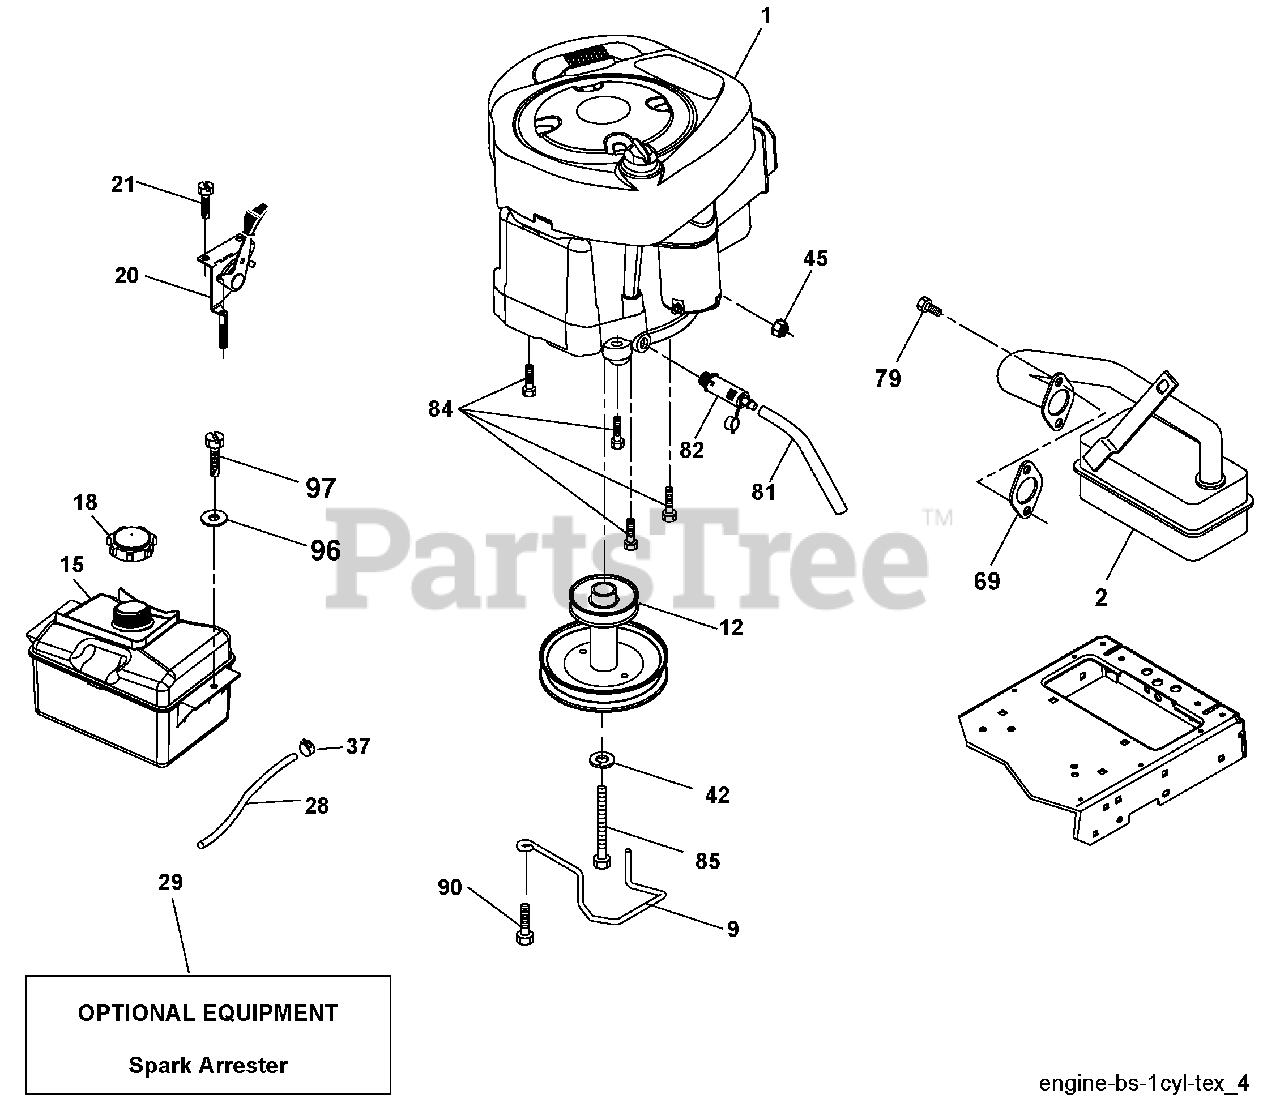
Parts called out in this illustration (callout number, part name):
2	Muffler
9	Keeper Belt Engine
12	Pulley Engine
15	Tank Fuel 1.50
18	Cap Asm.
20	Control Throttle/Choke
21	Screw #10 x 0.750 BOS Thread
28	Fuel Line
29	Spark Arrester Kit
37	Clamp Hose
42	Washer Lock 7/16
45	Nut Keps Hex 1/4-20 unc
69	Gasket
79	Screw Socket Hd. 5/16-18 x .75
81	Tube Drain Oil Easy
82	Plug Drain Oil
84	Screw 3/8-16 x 1-1/4
85	Bolt Hex 7/16-20 x 4 x Gr. 5-1.5
90	Screw 3/8-16 x 1.0
96	Washer 9/32 x 7/8 x 16 Ga.
97	Screw 1/4 - 20 x 3/4
